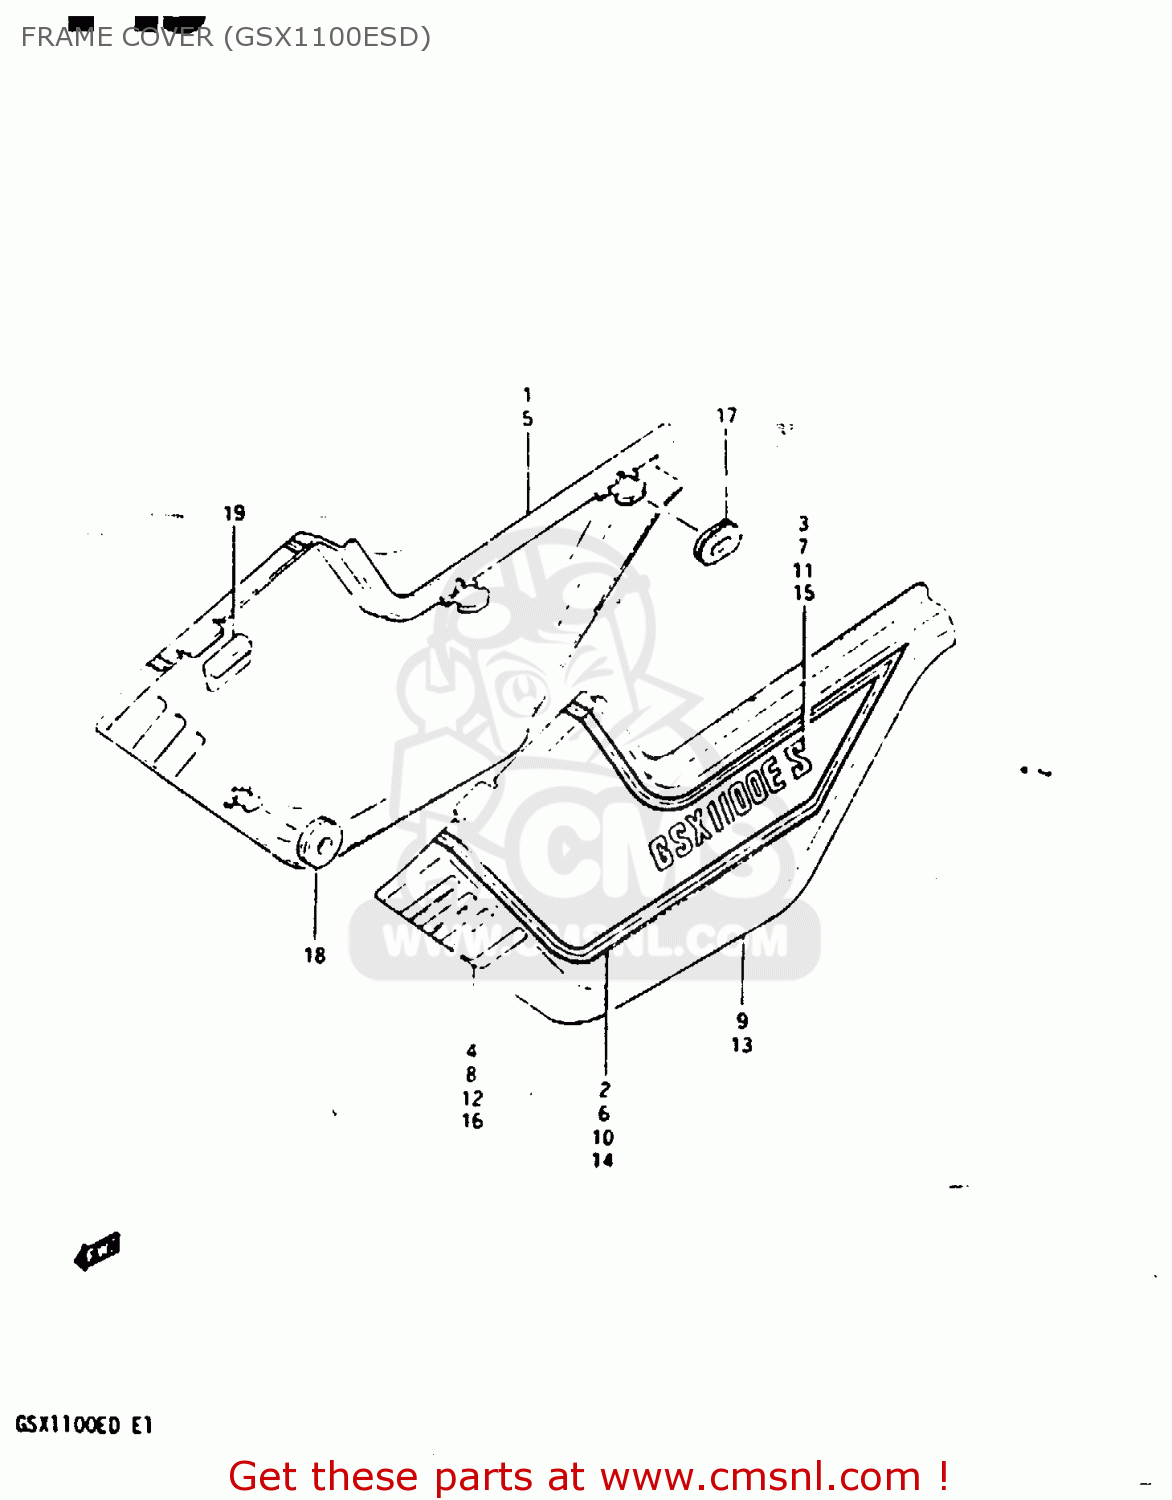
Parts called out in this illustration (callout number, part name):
1	COVER, FRAME RH
2	TAPE SET,FRAME COVER
3	EMBLEM, LH
4	LABEL, DENT
5	COVER, FRAME RH
6	TAPE SET,FRAME COVER,RIGHT
7	EMBLEM,FRAME COVER
8	LABEL, DENT
9	COVER, FRAME LH
10	TAPE SET,FRAME COVER,LEFT
11	EMBLEM, LH
12	EMBLEM,FRAME COVER,CENTER
13	COVER, FRAME LH
14	TAPE SET,FRAME COVER
15	EMBLEM,FRAME COVER
16	EMBLEM,FRAME COVER,CENTER
17	CUSHION
18	CUSHION
19	CUSHION,FRAME COVER
